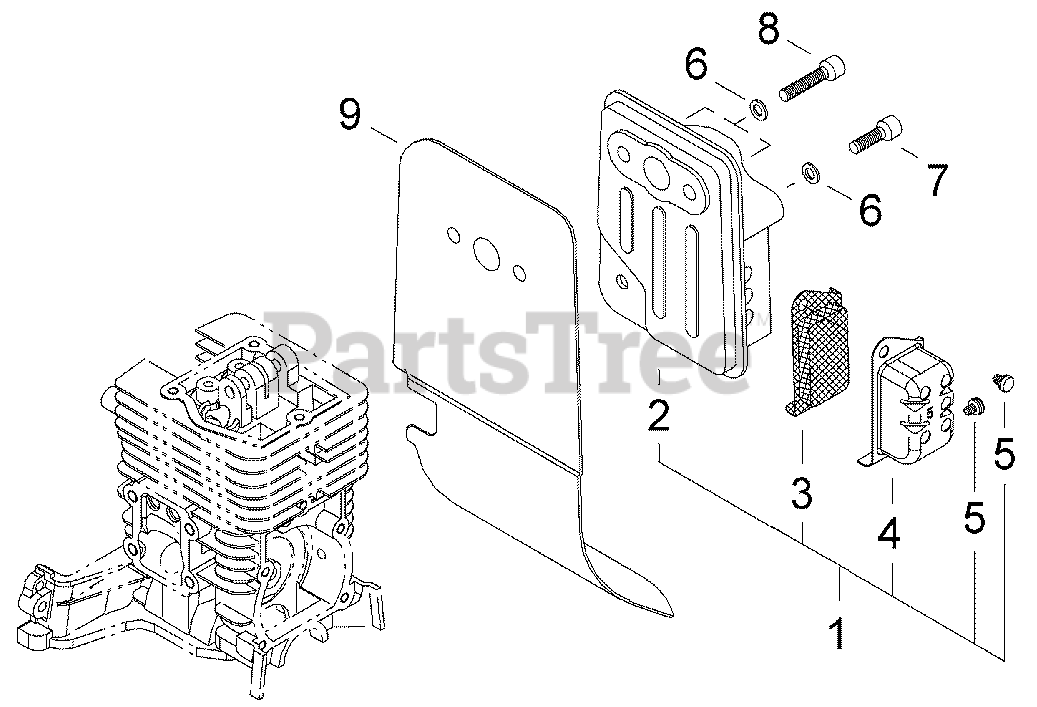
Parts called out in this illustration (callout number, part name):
1	MUFFLER ASSY
2	MUFFLER
3	SCREEN, SPARK ARRESTER
4	GUIDE, EXHAUST
5	SCREW M4×6
6	WASHER, FLAT 5.5×10×0.8
7	BOLT 5×16
8	BOLT M5×25
9	HEAT SHIELD, EXHAUST
